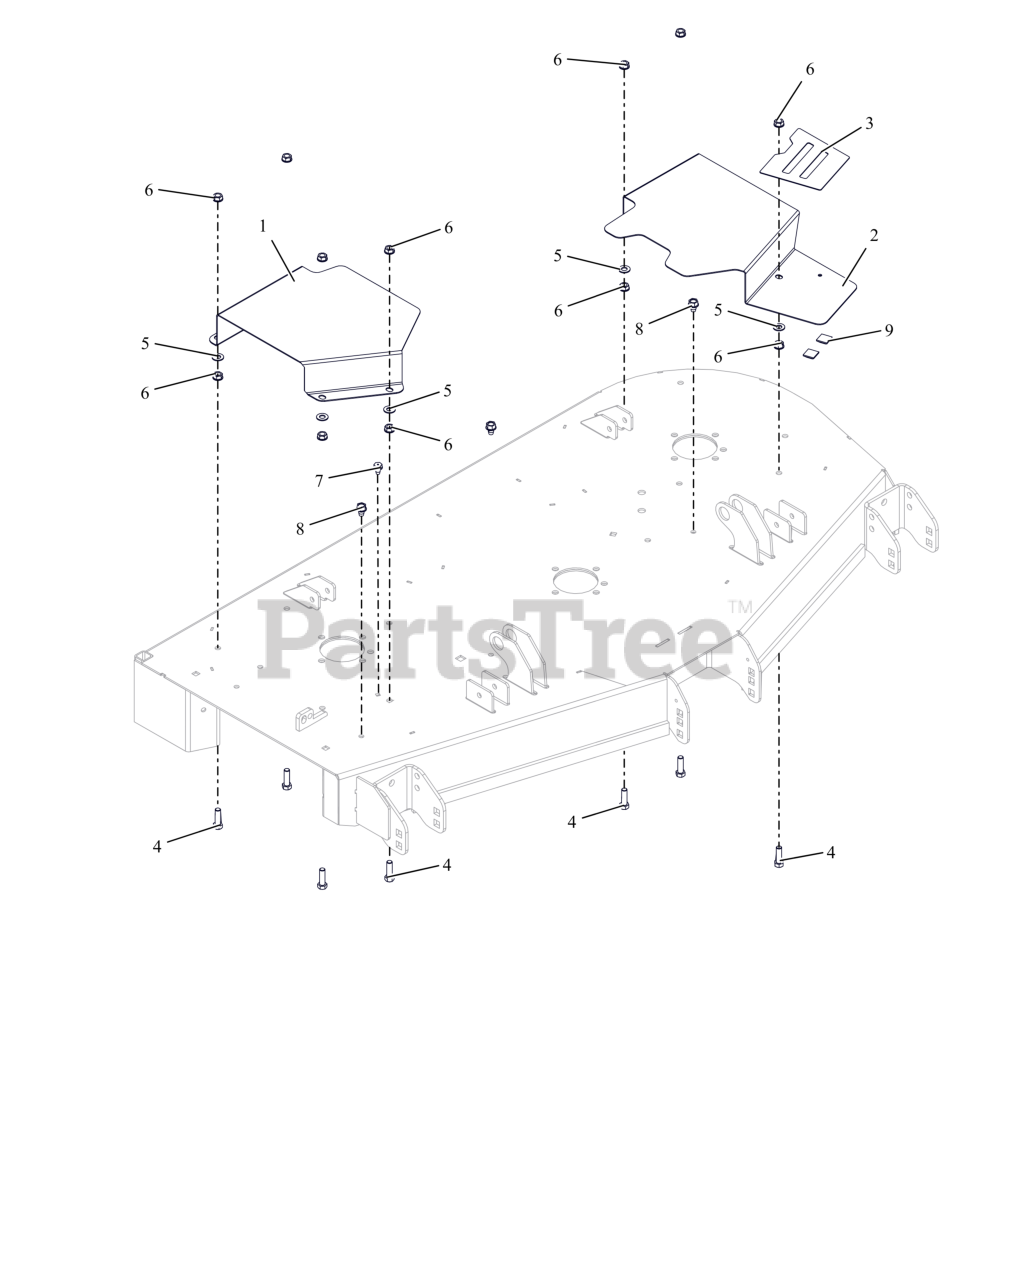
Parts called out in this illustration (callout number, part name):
1	COVER, BELT 52" & 60" RIGHT
2	COVER, BELT 52" LEFT
3	GRIP, TAPE 52-60 BELT COVER
4	BLT, HEX .38-16X1.25 G5 ZCC
5	WSHR,FLT .406X.812X.065 ZCC
6	NUT, SPNLK-FLG .38-16 G5 ZCC
7	SCR,TAP .312-18X.50 HWH TR ZCC
8	SCR,TAP .375-16X.50 HWH TR ZCC
